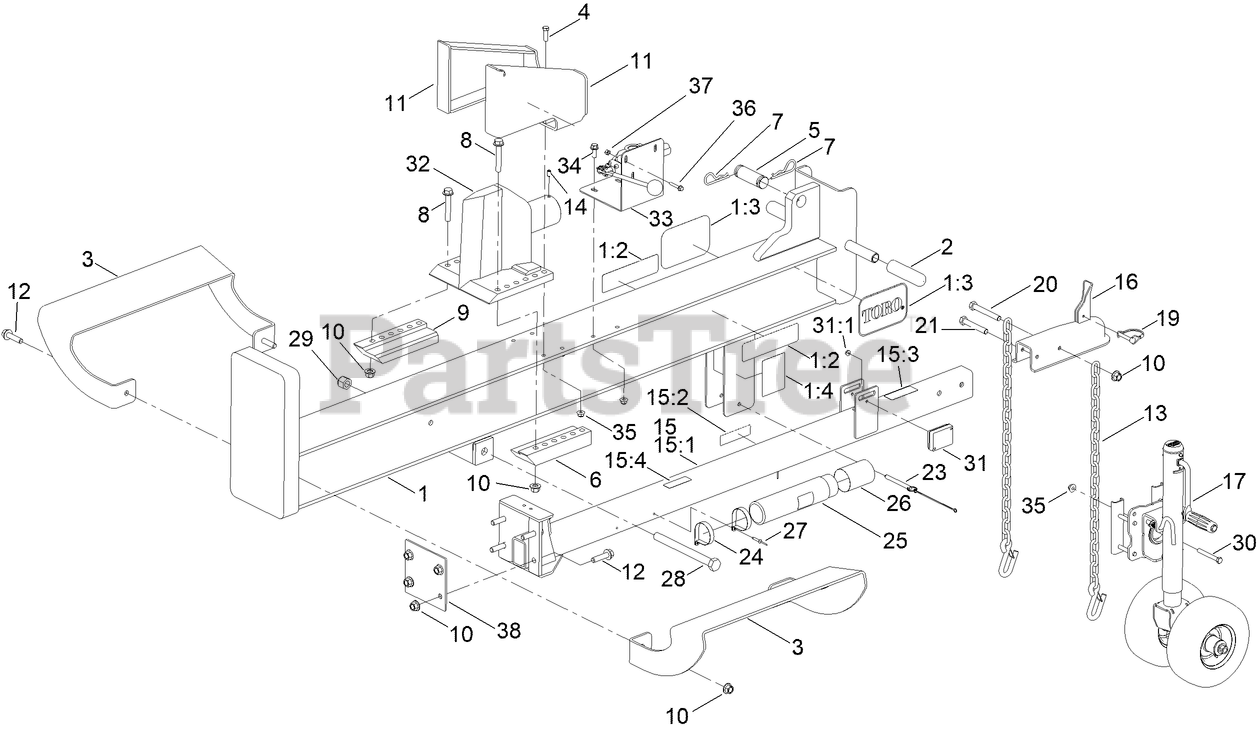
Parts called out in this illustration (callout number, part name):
1	BEAM ASM
1:3	DECAL
1:4	DECAL-WARNING, PIN
2	GRIP-HANDLE
3	PLATE-CATCH
4	SCREW-HH
5	PIN-PIVOT
6	BAR-SLIDE, LH
7	PIN-HAIR
8	SCREW-HF
9	BAR-SLIDE, RH
10	NUT-LOCK
11	DISLODGER BRACKET ASM
12	SCREW-HF
13	CHAIN-SAFETY, TRAILER
14	SCREW-SET
15	DECAL ASM - TUBE
15:1	TONGUE ASM [RED]
15:2	DECAL-ARRESTOR, SPARK
15:3	DECAL-CAUTION
15:4	DECAL-WARNING, PINCH POINT
16	RECEIVER-HITCH, BALL
17	JACK ASM
19	PIN-LOCK
20	SCREW-HH
21	SCREW-HH
24	CLAMP-R
25	TUBE-MANUAL
26	CAP-HOUSING
27	RIVET-BLIND
28	BOLT-HH
29	NUT-LOCK, NI
30	SCREW-HH
31	LAMP-MARKER, FRONT SIDE
31:1	NUT-KEPS
32	WEDGE ASM
33	BRACKET-VALVE
34	SCREW-HHF
35	NUT-HF, NI
36	SCREW-HHF
37	NUT-LOCK, NI
38	PLATE - BACKING
